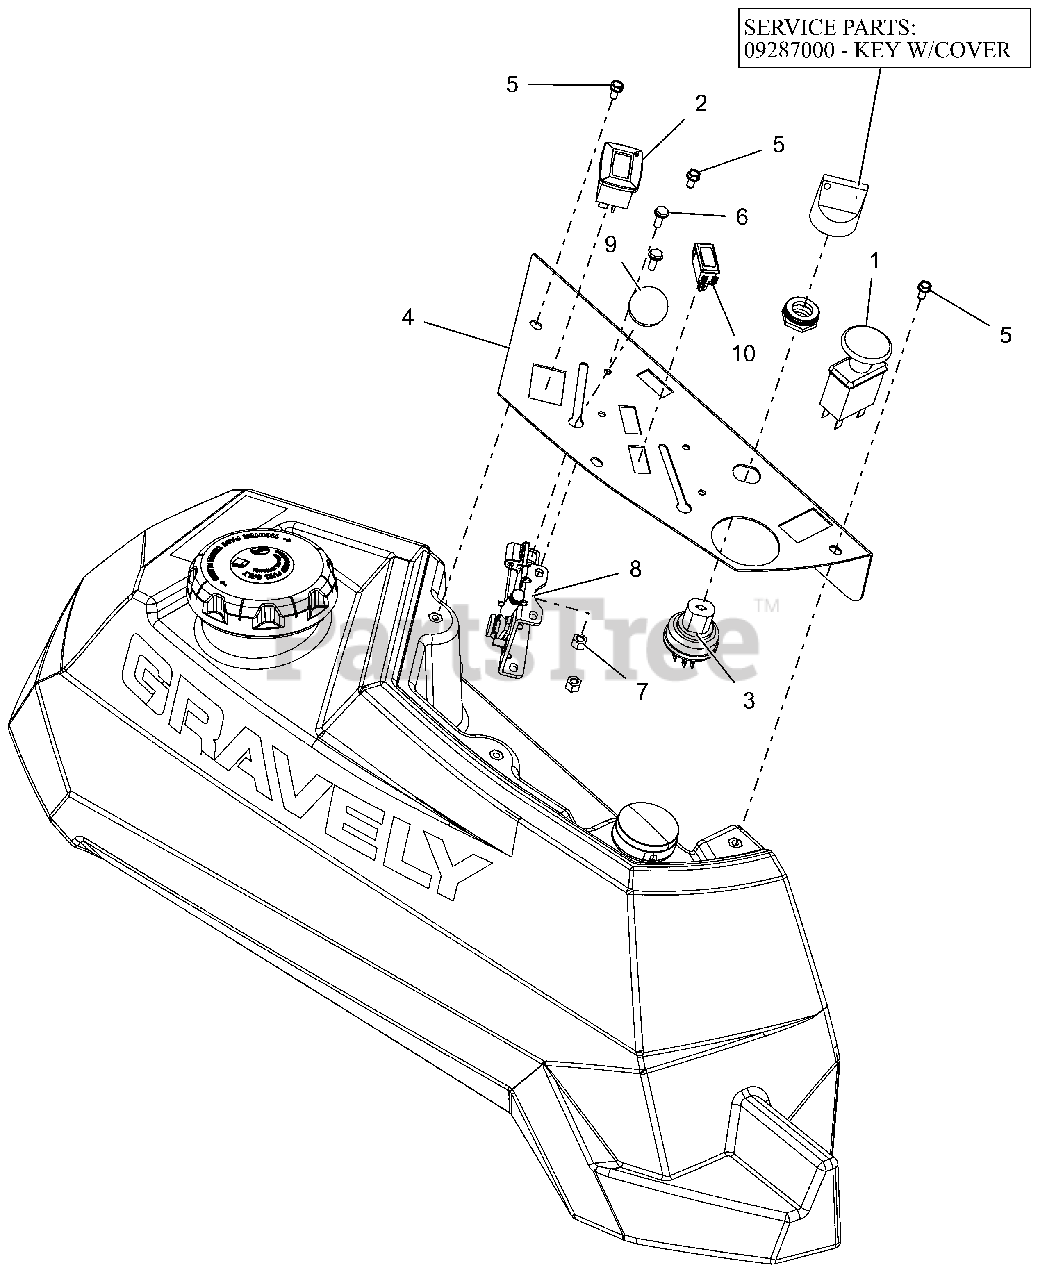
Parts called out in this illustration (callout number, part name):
1	SWITCH, CLUTCH
2	METER, HOUR W/MAINTENANCE
3	SWITCH, IGNITION
4	PT100 CONTROL PANEL - RED
5	SCR-MCH 10-24X.38 HWHSTAINLESS
6	@SCR-MCH 10-24X.50 HWH YWZC
7	@NUT-LK-NYL 10-24 W/INSRT YWZC
8	CABLE, PRO-CONTROL 31.50"
8	CABLE, PRO-CTRL 35.50"
9	KNOB-CONTROL-BLACK .38-16X.50
10	LIGHT,INDICATOR
11	KEY, W/ SHIELD
